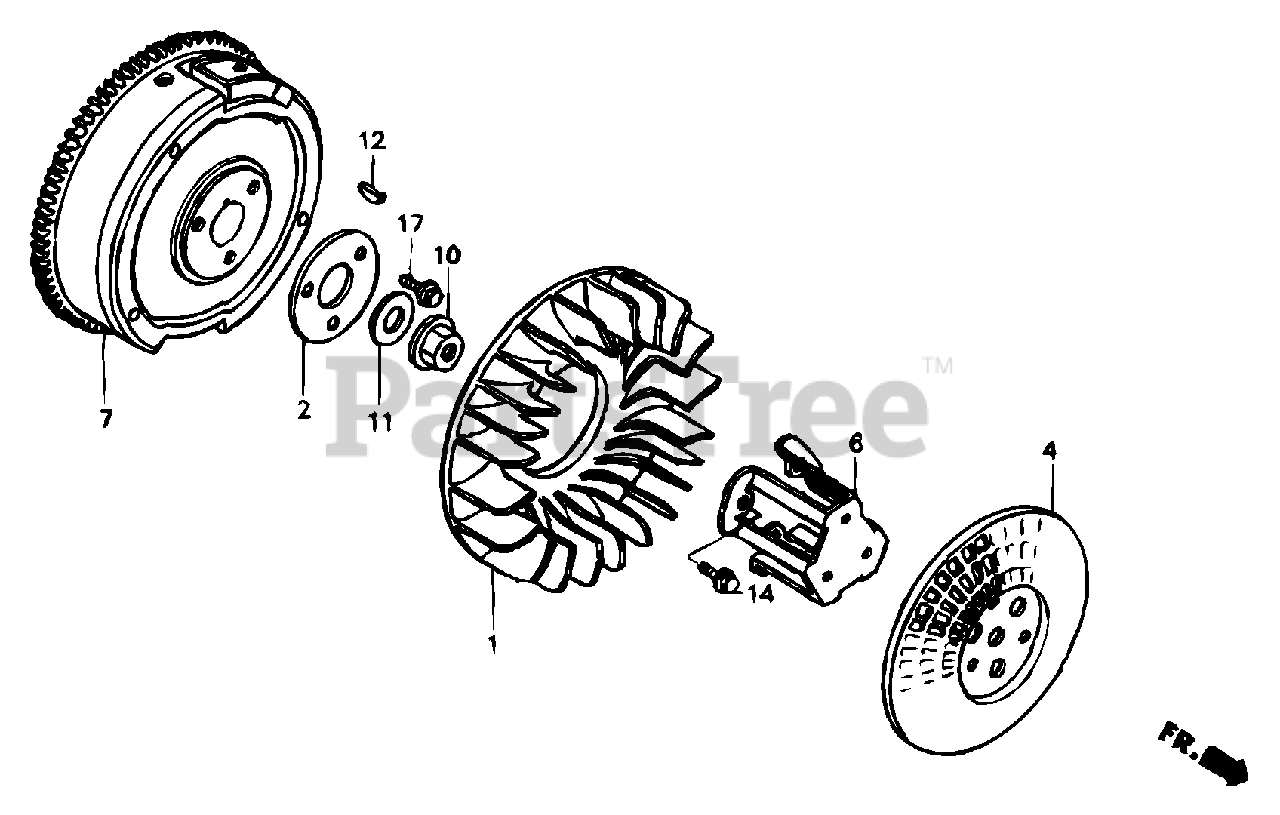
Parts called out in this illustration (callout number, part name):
1	Fan, Cooling
2	Plate, Cooling Fan Setting
4	Grid, Screen
6	Holder, Screen Grid
10	Nut, Flange (20mm)
11	Washer (20mm)
12	Key, Special Woodruff (25x18)
14	Bolt, Flange (8x16)
17	Bolt, Flange (8x16)
